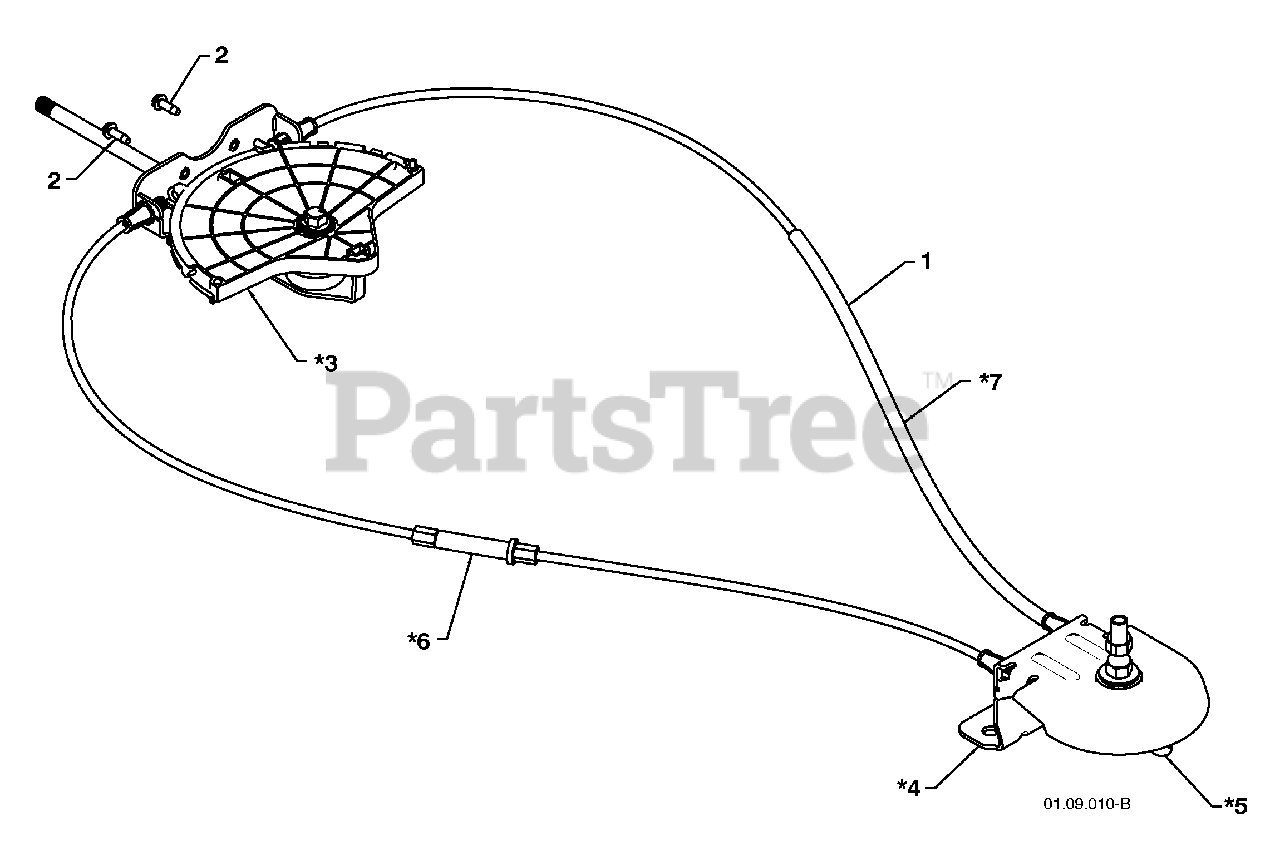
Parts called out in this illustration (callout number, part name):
1	LEVER/CABLE ROTATOR ASSEMBLY
2	SCREW 10-24 X .625
3	ROTATOR HEAD
4	ROTATOR PIVOT BRACKET
5	PULLEY PIVOT
6	CABLE ASSEMBLY ADJUSTABLE
7	CABLE ASSEMBLY HEAT SHIELD
